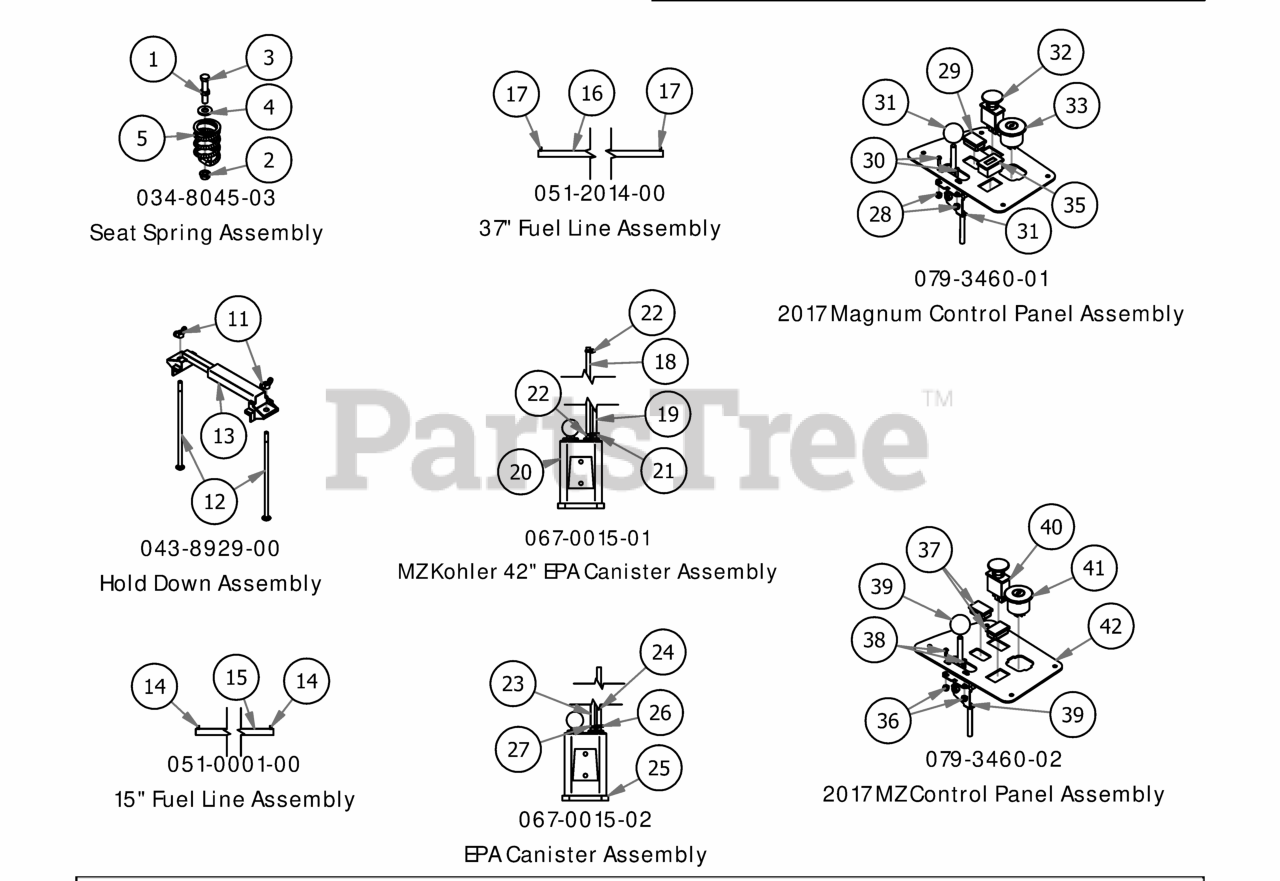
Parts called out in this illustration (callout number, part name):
1	3/8-16 Half Jam Nut
2	3/8" Flange Nut
3	3/8"-16 x 2" Gr 5 Hex Bolt
4	3/8" Flat Washer
5	Seat Spring
11	1/4" Wing Nut
12	1/4-20 X 8 Carriage Bolt
13	Battery Hold Down
14	1/4 Fuel Hose Clamp
15	1/4 Fuel Line
16	37" 1/4 Fuel Line
17	1/4 Fuel Hose Clamp
18	3/16 Vinyl Tubing, 53"
19	3/16" Clear Vinyl Tubing, 44"
20	Carbon Canister for Magnum/MZ
21	3/16" Vinyl Hose Clamp
22	8.6mm Hose Clamp
23	3/16 Vinyl Tubing, 44"
24	3/16" Clear Vinyl Tubing, 52"
25	Carbon Canister for Magnum/MZ
26	3/16" Vinyl Hose Clamp
27	8.6mm Hose Clamp
28	10-24 Nylon Insert Locknut Zinc Orange Nylon
29	Light Plug
30	10-24 X 5/8 BS Button Head Bolt
31	Throttle Lever Assembly
32	PTO Engager
33	Ignition Switch
34	Control Panel
35	Tachometer
36	10-24 Nylon Insert Locknut Zinc Orange Nylon
37	Light Plug
38	10-24 X 5/8 BS Button Head Bolt
39	Throttle Lever Assembly
40	PTO Engager
41	Ignition Switch
42	Control Panel
